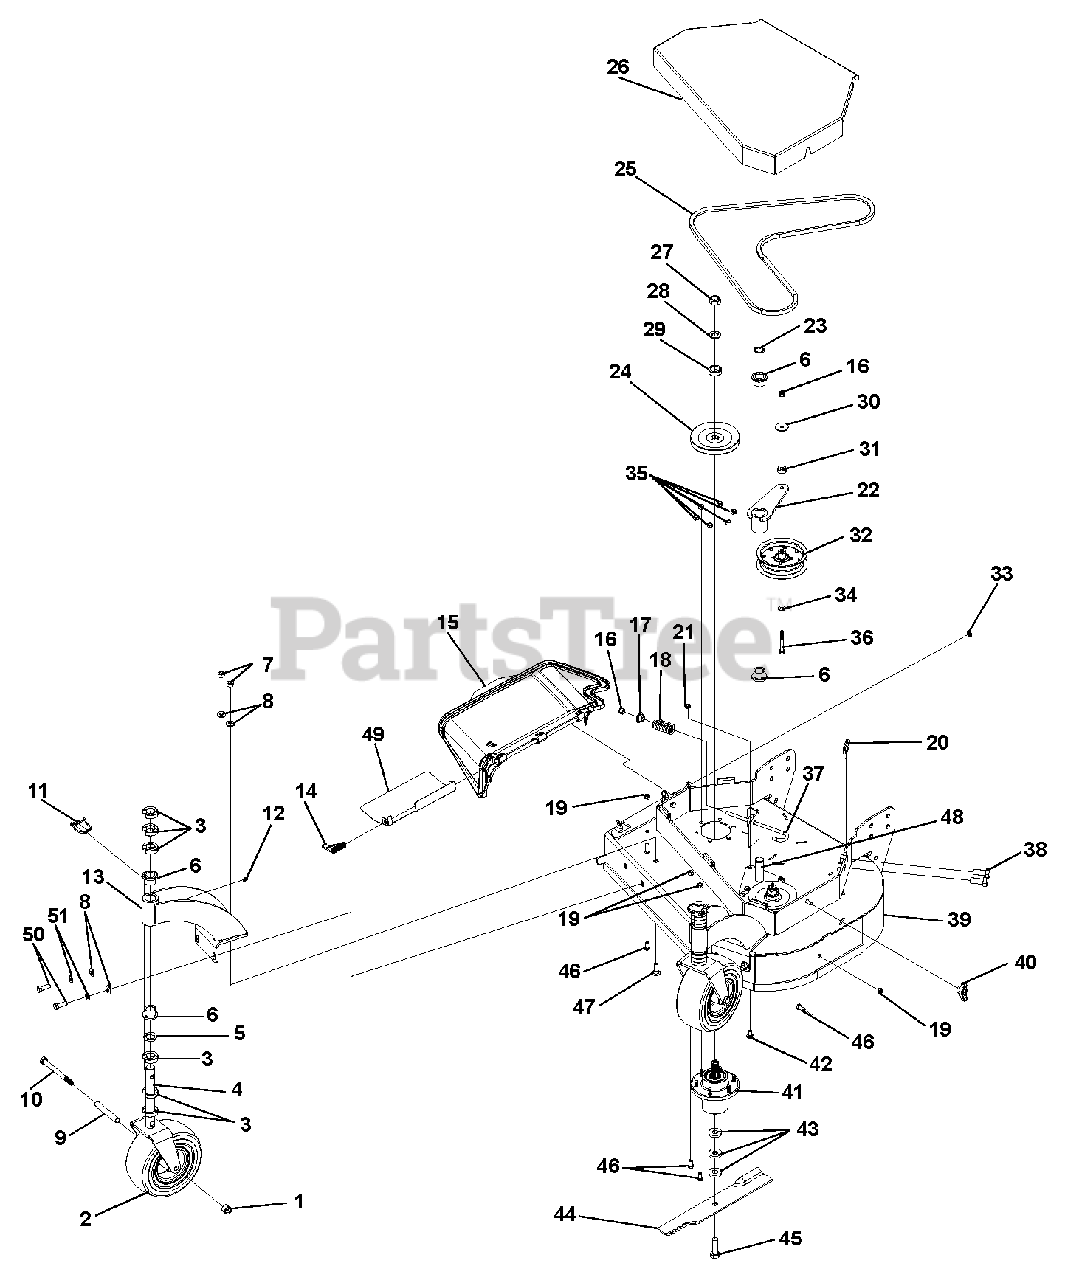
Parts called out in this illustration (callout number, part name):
1	Locknut, .50-13 Nyloc
2	Assembly, Wheel and Tire 9 x 3.5
3	C-Spacer, 1.00 x 1.77 x .500
4	Weldment, Caster Yoke W/GRVLY Paint
5	Bushing, 1.03 x 1.50 x .179
6	Bearing, Flange 1.00 x 1.25 x 1.00
7	Locknut, .4375-14 Crown
8	Washer, .375 Regular Flat
9	Tube, Caster Axle
10	Bolt, .50-13 x 5.50 Hex 5
11	Pin, LNC .438 x 2.00
12	Fitting, .25-28 STRGT Grease Zerk
13	Weldment, Caster SUPP w/Gravely Paint
14	Spring, Torsion .460 x .138
15	Chute Discharge Assembly
16	Locknut, .38-16 Nyloc
17	Keeper, Spring
18	Spring, COM 1.22 x .162 x 2.50
19	Locknut, .38-16 Crown
20	Trim, 1/4" Trim-LOK
21	Nut, Locking-Jam-Center .375-16
22	Weldment, Idler Arm
23	Snap Ring, 1.00 x .042 External
24	Pulley, Narrow Spline
25	Belt, 5L 76.15 Banded
26	Shield, Belt 32/36 Gear Gravely
27	Locknut, .75-16 Crown
28	Washer, .75 x 1.3125 x .120
29	Spacer, Spindle Top-Pulley
30	Washer, Flat .375 x 1.50 x .063
31	Bushing, .380 x 1.00 x .410
32	Pulley, Flat 5.00 x .375 W/BRG
33	Retainer
34	Washer, .406 x .813 x .065 Flat
35	Nut, .38-16 Standard Hex Grade 5
36	Bolt, .38-16 x 2.75 Hex 5
37	J-Bolt, .38-16 x 7.88
38	Bolt, Hex .625-11 1.5 Grade 8
39	Assembly, Deck Gravely 32" with Decals
40	Knob, .38-16 Insert
41	Assembly, Spindle Housing
42	Bolt, .38-16 x .750 CRG 5 LN
43	Washer, .630 x 1.50 x .250 Flat
44	Blade, 16.500 x .80 Lift
45	Bolt, .625-11 x 2.00 Hex 8
46	Bolt, .38-16 x .750 Hex 5
47	Bolt, .4375-14 x 1.25 CRG 5
48	Weldment, Idler Pivot Mount
49	Deflector, Discharge Chute
50	Bolt, .4375-14 x 1.25 Hex 5
51	Washer, .438 Medium Spring Lock
